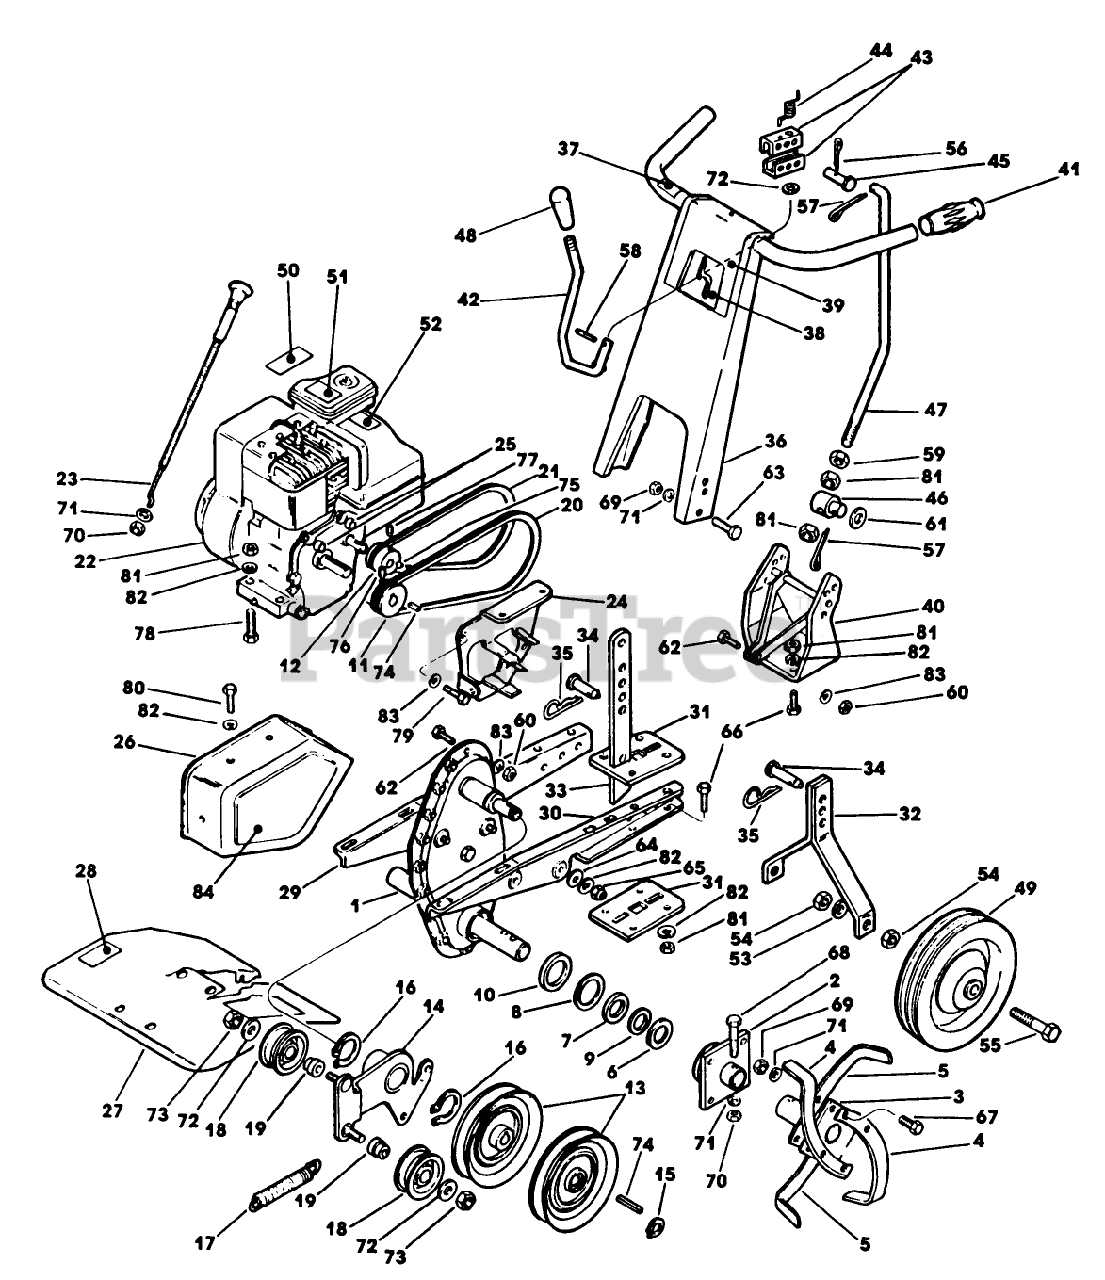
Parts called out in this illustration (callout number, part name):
2	TINE HUB AY
4	TINE - RH
5	TINE - LH
7	SEAL-FELT
8	SEAL - FELT
9	WASHER
10	WASHER BACK-UP
14	ARM ASSEMBLY
15	RING-RETAINING
17	SPRING-DRIVE
19	SPACER
20	V-BELT (207159)
23	THROTTLE CONTROL
33	DEPTH CONTROL
35	PIN - SPRING CLIP
40	SUPPORT AY-HANDLE *B
44	SPRING CONTROL LEV
49	WHEEL & TIRE ASM
60	NUT
65	NUT
66	SCREW - HEX
69	NUT
71	WASHER
72	WASHER
73	NUT
75	Key, Woodruff
76	SET SCREW
81	NUT SS
